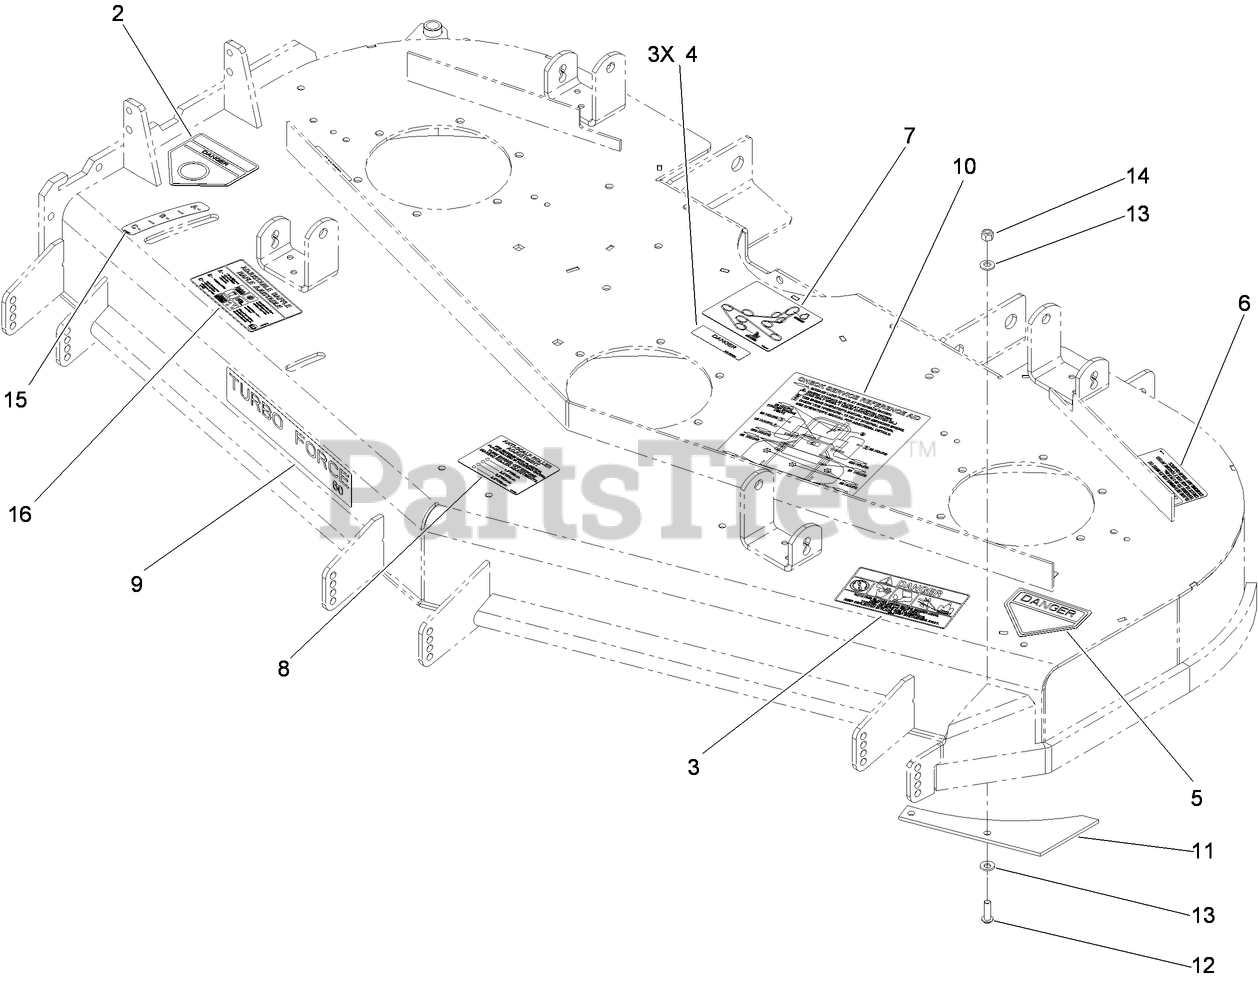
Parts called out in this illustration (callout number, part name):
2	DECAL-DANGER
3	DECAL-DANGER, THROWN OBJECT
4	DECAL-COVER, MISSING
5	DECAL-DANGER
6	DECAL-TORQUE
7	Decal-Routing, Belt
8	DECAL-SCALP, ANTI
10	DECAL-SERVICE, CHECK
11	PLATE-TURBO
12	SCREW-HSBH
13	WASHER-SPRING
14	NUT-LOCK, NI
15	DECAL-SETTING, BAFFLE
16	DECAL-ADJUSTMENT, BAFFLE
